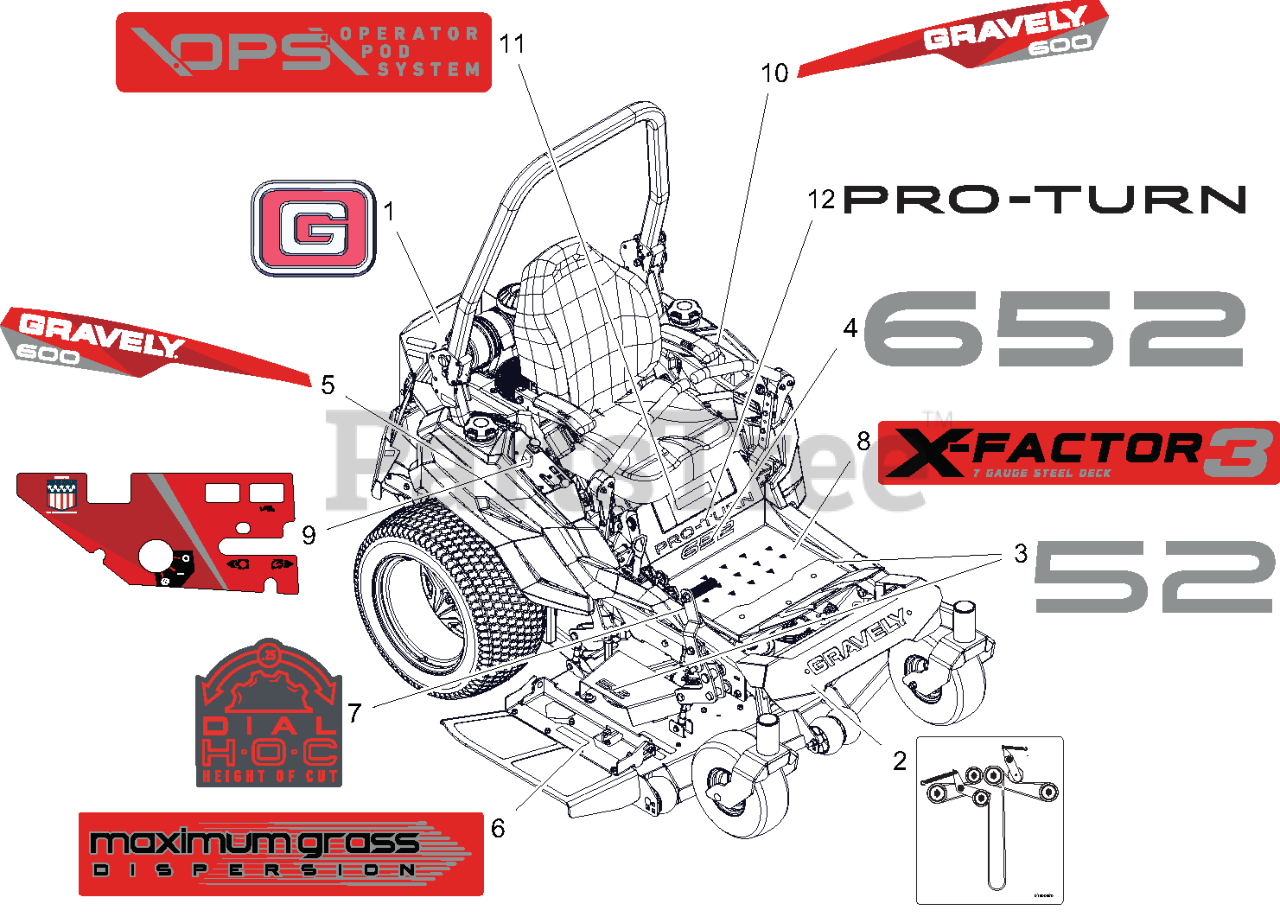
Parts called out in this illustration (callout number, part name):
1	DECAL, GRAVELY BRAND
2	DCL,BELT ROUTE-RH BK-SIDE IDLR
3	DECAL, DECK - 52
4	DECAL, PT652
5	DECAL, GRAVELY TANK - RH
6	DECAL, DECK - MAX GRASS
7	DECAL, COVER - HOC
8	DECAL, DECK - X-FACTOR 3
9	DECAL, CONTROL PANEL
10	DECAL, GRAVELY TANK - LH
11	DECAL, OPS
12	DECAL, PRO TURN
